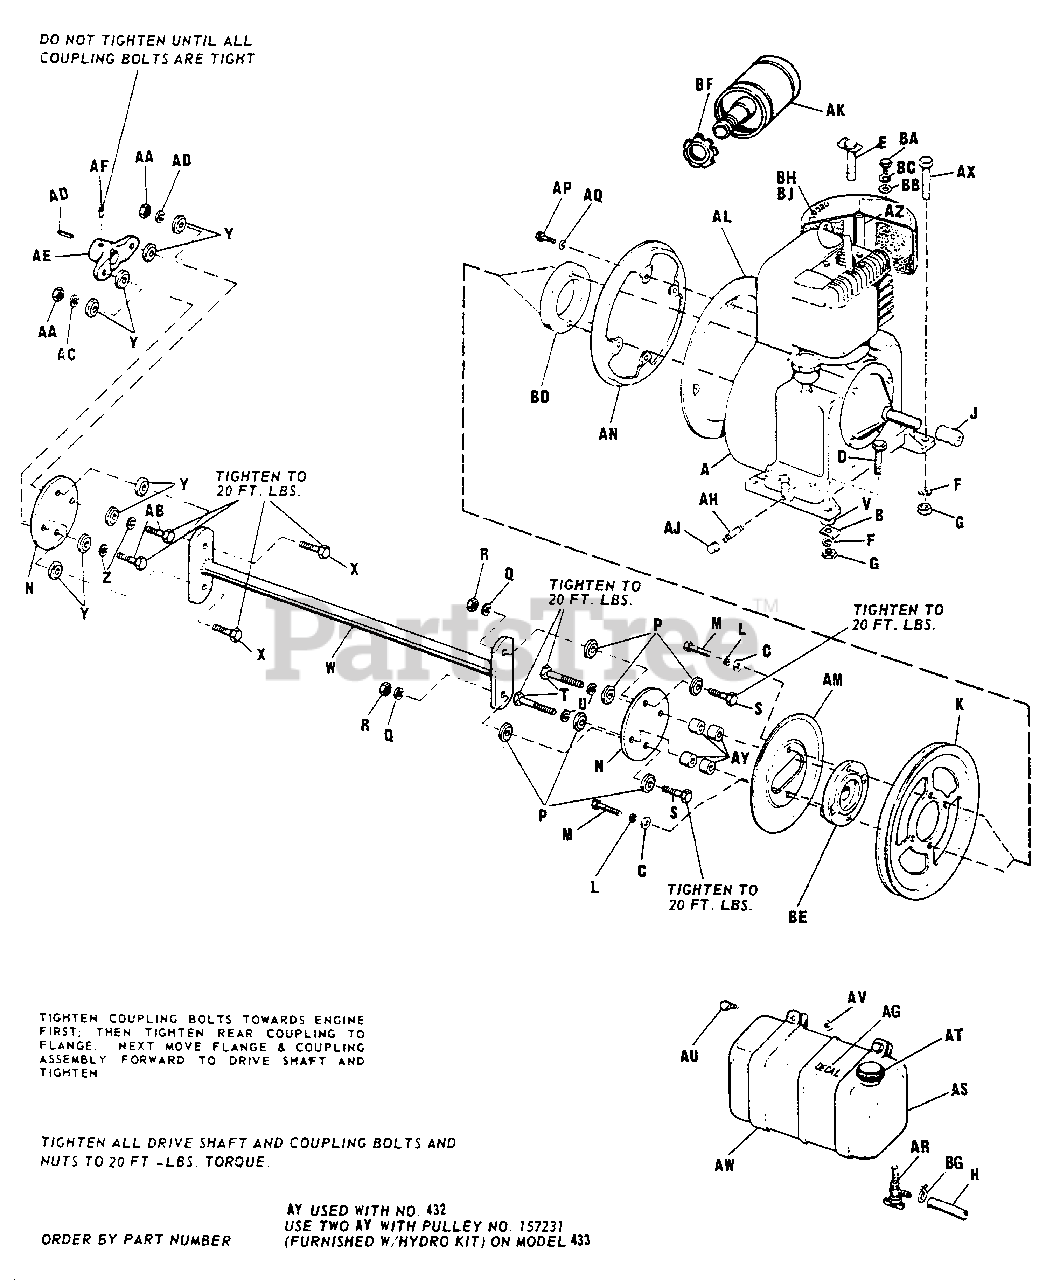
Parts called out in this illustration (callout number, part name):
A	Engine, Briggs & Stratton Model 243431,Type 0123 (157095)* (157558)à
B	Axle Stop
C	Plain Washer, 5/16"
D	Hex. Cap Screw, 3/8"-16 x 1-3/4" lg.
E	Screw Assembly, Engine, L.H. Rear (157556)** (157556)à
F	Lock Washer, 3/8"
G	Full Hex. Nut, 3/8"-16
H	Fuel Hose (Flexible)
J	Crankshaft Extension Guard
K	Engine Pulley (157484)à
L	Lock Washer, 5/16"
M	Hex. Cap Screw, 5/16-18 x 2" lg. (715025)*
N	Coupling (154194)*
P	Special Washer (154192)*
Q	Lock Washer 3/8"
R	Full Hex. Nut, 3/8"-16
S	Hex. Cap Screw 3/8"-3/16 x 1-1/4" lg. (705009)*
T	Hex. Hd. Capscrew, 3/8"-16 x 2" lg. (715043)à
U	Lock Washer 3/8"
V	Plain Washer 3/8"
W	Drive Shaft Assembly
X	Hex. Cap Screw 3/8"-16 x 1-1/4" lg. (705009)*
Y	Special Washer (154192)*
Z	Lock Washer, 3/8"
AA	Full Hex. Nut, 3/8"-16
AB	Hex. Cap Screw 3/8"-16 x 1-1/4"
AC	Lock Washer, 3/8"
AD	Key (725504)*
AE	Drive Shaft Flange
AF	Cup Point Socket Head Set Screw, 3/8"-24 x 5/8"
AG	Decal (CAUTION)
AH	Pipe Nipple, 3/8" x 1" lg. (154350)*
AJ	Pipe Cap, 3/8"
AK	Exhaust Muffler (154379)*
AL	Flywheel Shroud
AM	Engine Screen (154477)*
AN	Shroud (Not used on 308 & 314)
AP	Hex. Cap Screw, 1/4"-20 x 1/2" (Not used on 308 & 314)
AQ	Lock Washer, 1/4" (Not used on 308 & 314)
AR	Shut-Off Valve
AS	Fuel Tank
AT	Fuel Tank Cap
AU	Hex. Hd. Capscrew, 1/4"-20 x 1-3/4"
AV	Full Hex. Nut 1/4"-20
AW	Tank Strap
AX	Hex. Hd. Capscrew 3/8"-16 x 2" lg.
AY	Spacer (4) (2 on 308 & 314)
AZ	Air Cleaner Spacer (157126)*
BA	Hex. Hd. Capscrew 1/4"-20 x 5/8"
BB	Plain Washer, 1/4"
BC	Lock Washer, 1/4"
BD	Flywheel Spacer (Not used on 308 & 314)
BE	Drive Hub
BG	Hose Clamp (FOR SERVICE ONLY)
